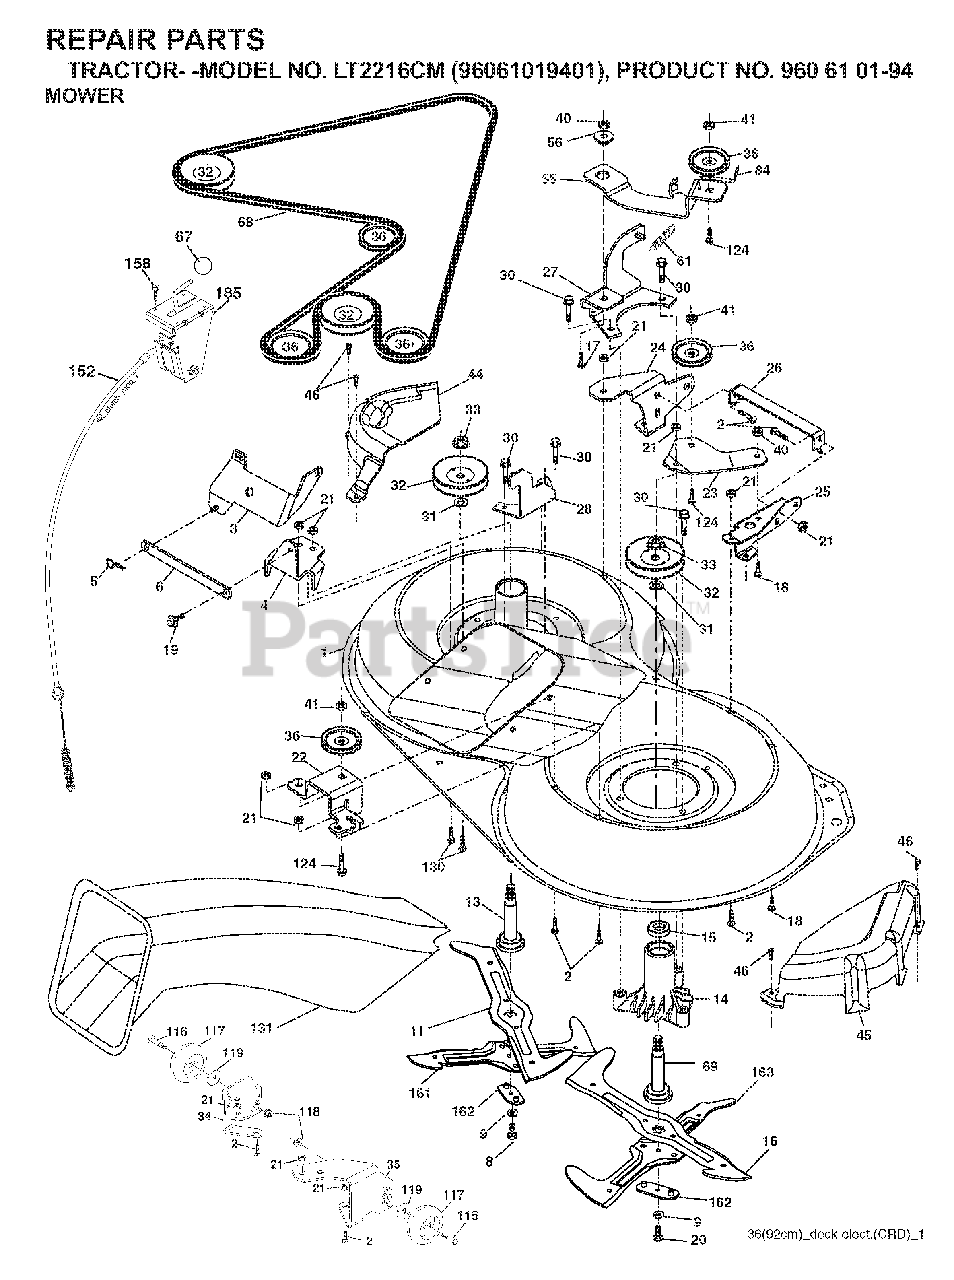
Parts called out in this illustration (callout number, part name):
2	BOLT
3	BRACKET
5	RETAINER-SPRNG RB
6	BAR SWAY
9	LOCKWASHER
10	WASHER.BLADE
13	SHAFT ASM VENT
14	HSG MANDREL
17	BOLT.3/8-14X1.25
19	BOLT SHD 5/16-18
21	LOCKNUT
24	BRACKET
25	BRACKET
28	BRACKET
30	SCREW, WASHER HEAD
31	WASHER.SPACER.MANDREL
32	PULLEY MANDREL
33	NUT.FLANGE.LOCK.TOP
36	PULLEY.IDLER.4.25
40	LOCKNUT
41	NUT LOCK FLG 3/8-16 UNC
45	MANDREL COVER
46	SCREW.1/4-20X5/8
56	SPACER.RETAINER.MOWER
67	KNOB T (3/8 HOLE)
69	SHAFT.ASM.W/LWR.BRG.RH.THREAD
84	KEEPER, BELT IDLER
116	BOLT.SHOULDER.3/8-16X3-5/8
117	WHEEL. GUAGE RALLY
118	NUT LOCK FLG 3/8-16 UNC
124	BOLT.3/8-16X1.50
131	CHUTE BAGGER
158	SCREW
185	HEAD ASM. CABLE CLUTCH
